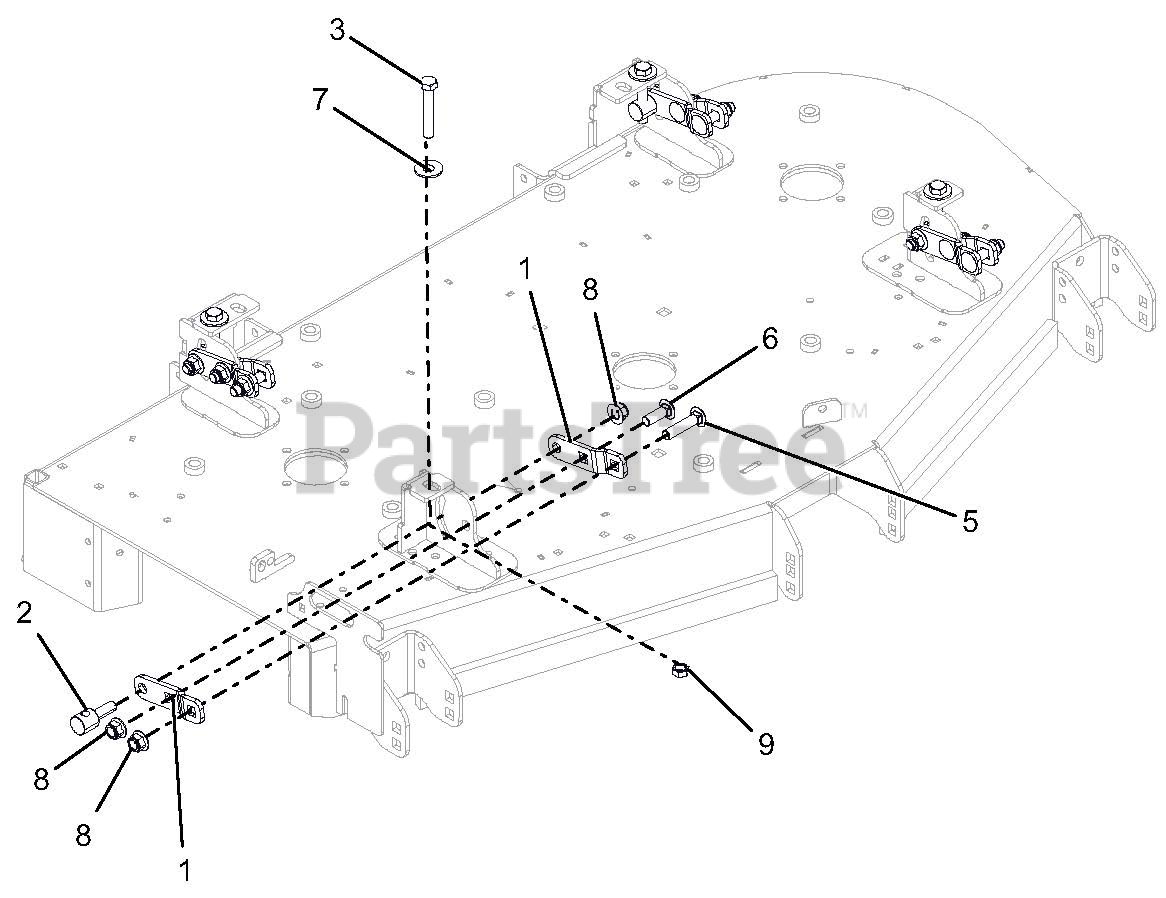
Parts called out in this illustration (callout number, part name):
1	BRKT, DECK LEVELING
2	TRUNNION, .50-13
3	BLT-HEX .50-13X3.00 GR5 FTH YWZC
5	BLT-RDHDSQNK .50-13X2.25 G5 Y
6	BLT-RDHDSQNK .50-13X1.50 G5 YWZC
7	WSHR-FL-STL.563X1.38X.109YWZC
8	NUT-LK-NYL-FLG .50-13 YWZC
9	NUT, JAM .500-13 YWZC
